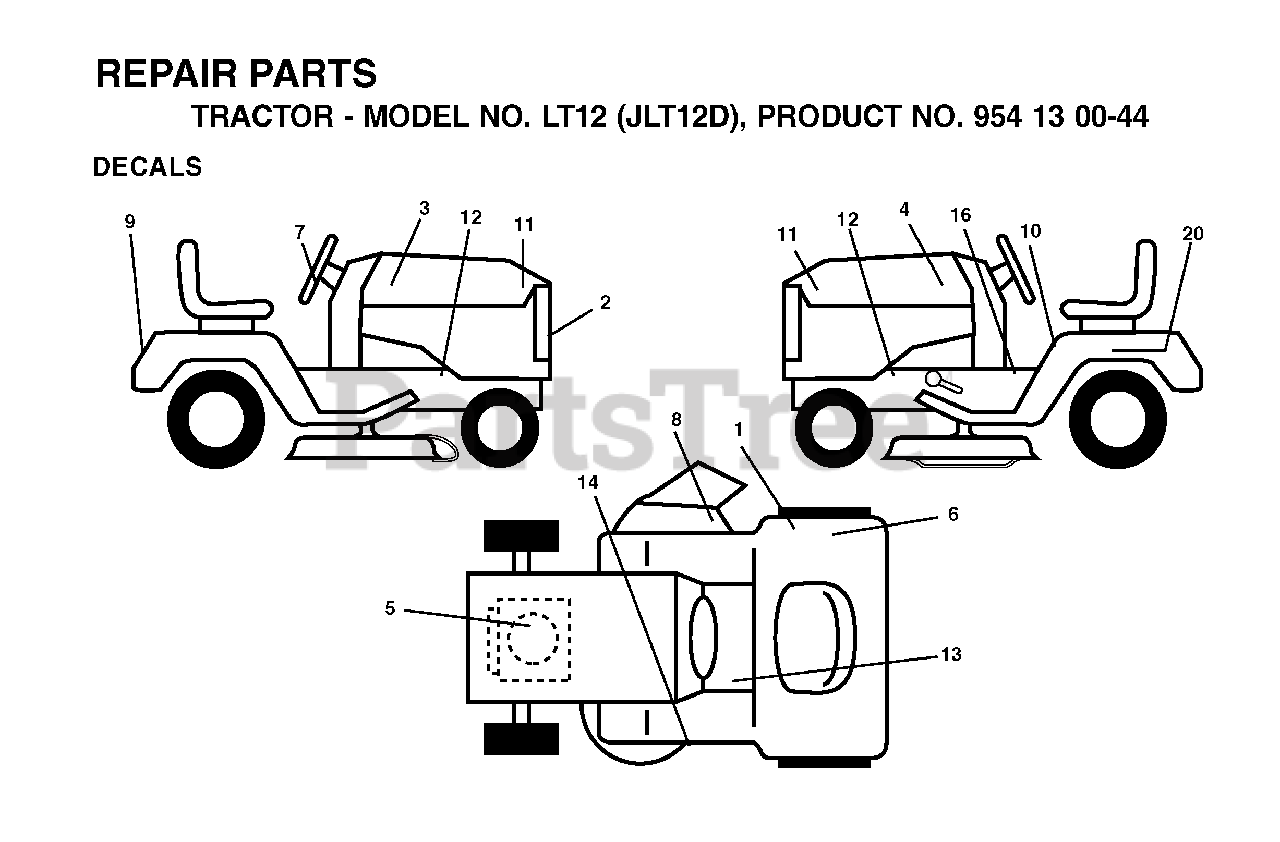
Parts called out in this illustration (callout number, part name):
1	DECAL CERTIFICATION
6	DECAL EUROPE STANDARD CE
8	DECAL MOWER CUT/FINGER
10	DECAL READ OWNER'S MAN SYMS
14	DECAL V-BELT SCHEMATIC
16	DECAL PARK BRAKE
20	DECAL BTRY SYMBOLS
